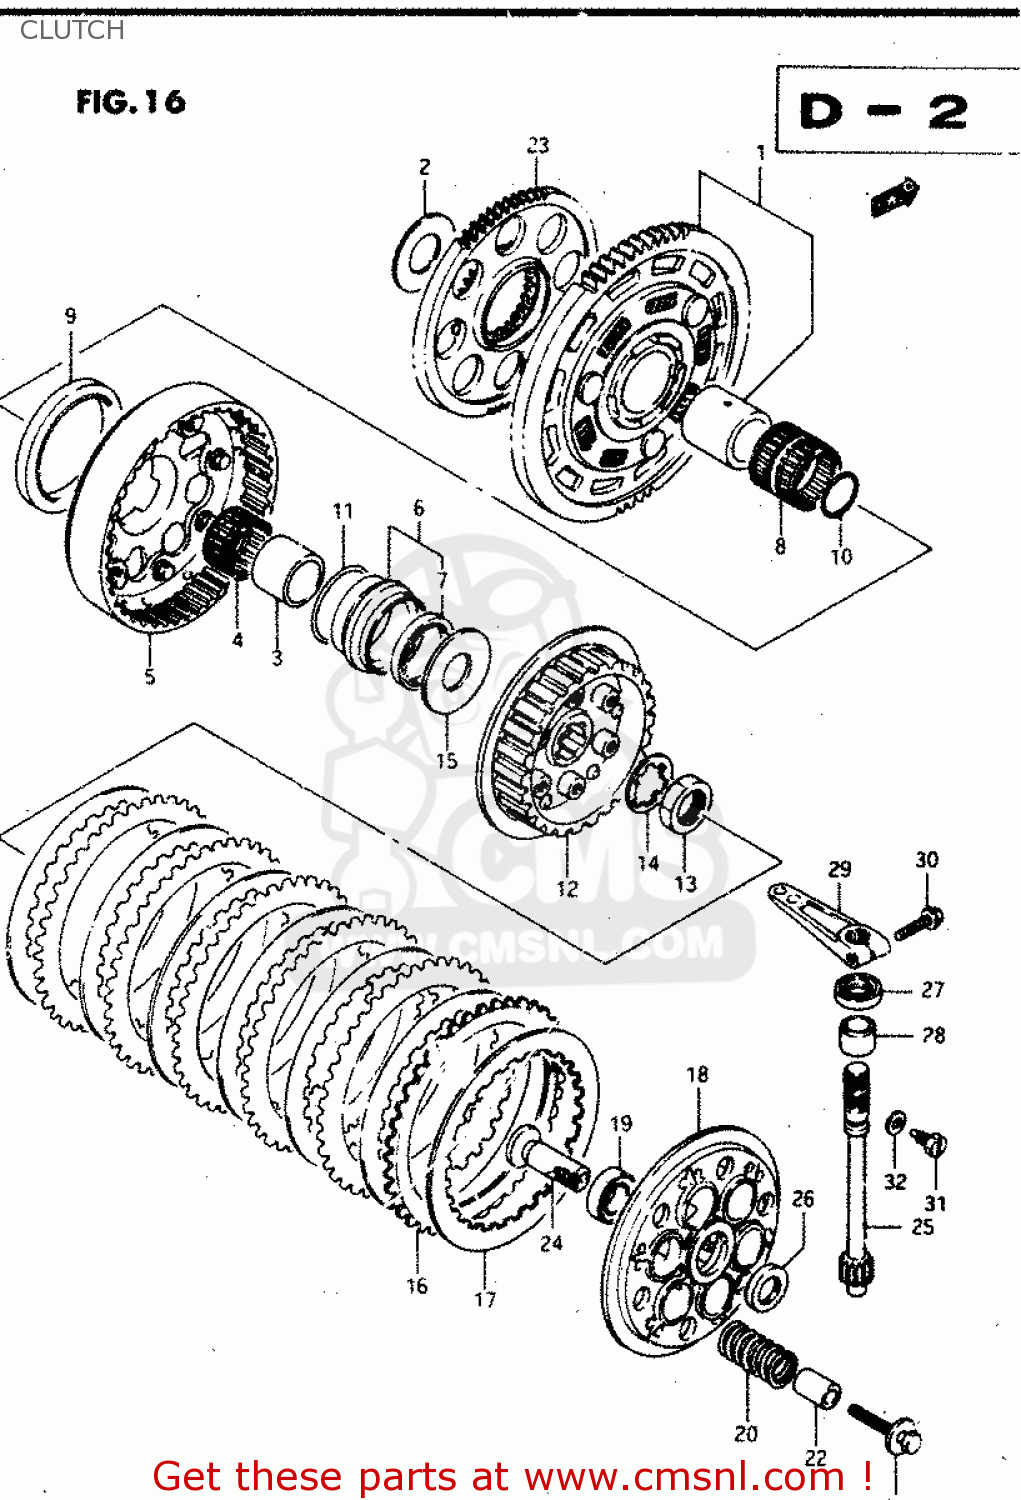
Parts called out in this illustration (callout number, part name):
1	GEAR ASSEMBLY,PRIMARY DRIVE
2	WASHER
3	SPACER (25X35X25)
4	ROLLER BEARING,PRIMARY DRIVE
5	HOUSING,CLUTCH
6	COLLAR,CLUTCH HOUSING
7	SEAL,OIL(35X45X6)
8	BEARING(35X40X35.8)
9	OIL SEAL
10	O-RING
11	O-RING (D:2.4 ID:45.7)
12	HUB, SLEEVE
13	NUT
14	WASHER,LOCK
15	WASHER (22X51X2.5)
16	PLATE,CLUTCH DRIVE
17	PLATE,CLUTCH DRIVEN
18	PLATE,CLUTCH PRESSURE
19	SPRING,CLUTCH
20	SPRING
21	BOLT
22	SPACER(6.2X12.6X21)
23	GEAR,GENERATOR DRIVE
24	RACK,CLUTCH RELEASE
25	PINION,CLUTCH RELEASE
26	SEAL,OIL(15X25X4)
27	SEAL,OIL(13X23X5)
28	BUSHING,CLUTCH RELEASE PIN
29	ARM,CLUTCH RELEASE
30	BOLT
31	BOLT
32	WASHER
